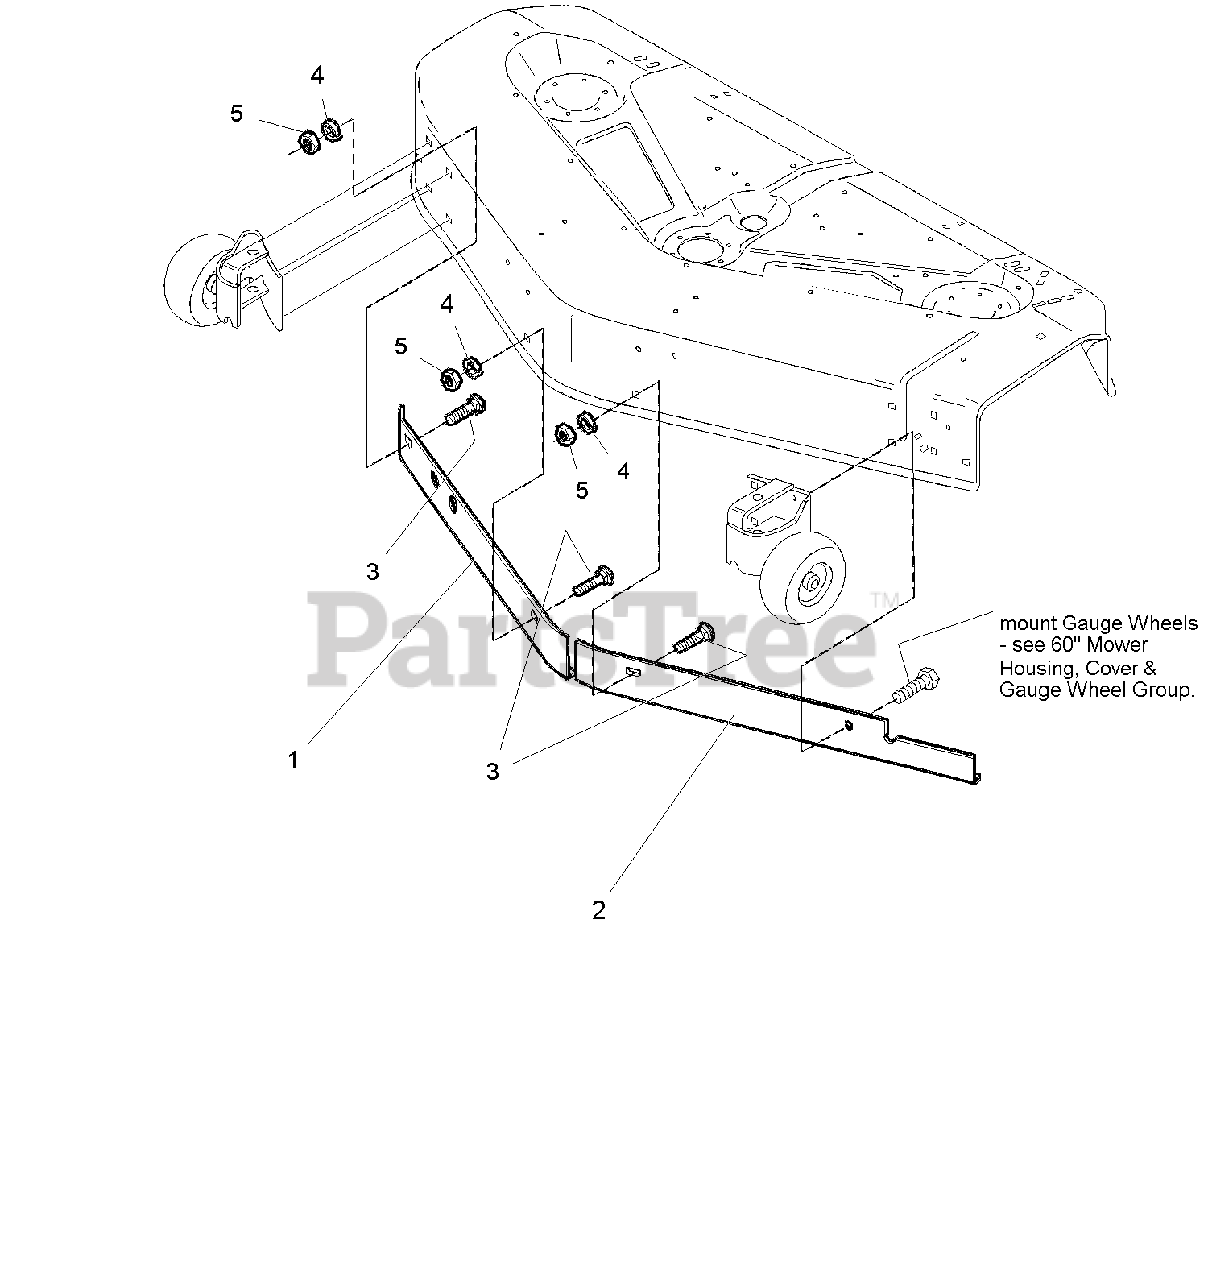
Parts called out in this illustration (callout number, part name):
1	BAFFLE, RH
2	BAFFLE, LH
3	CARRIAGE BOLT, 3/8-16 x 1
4	LOCKWASHER, 3/8
5	NUT, 3/8-16
